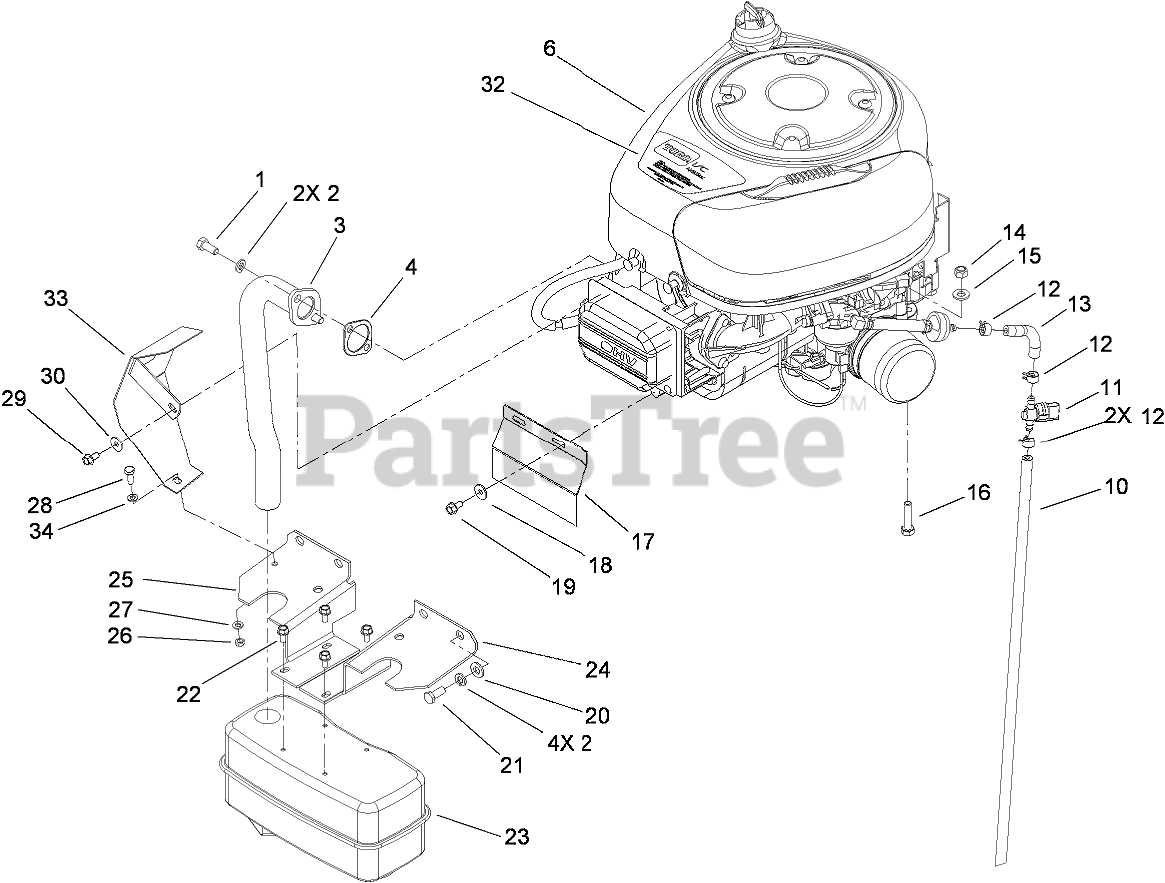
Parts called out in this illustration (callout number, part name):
1	SCREW-HH
2	WASHER-LOCK, SPRING
3	TUBE-EXHAUST
4	GASKET-EXHAUST
10	LINE-FUEL
11	VALVE-TANK, FUEL
12	CLAMP-LINE, FUEL
13	LINE-FUEL
14	NUT-LOCK, NI
15	WASHER-PLAIN
16	SCREW-HH
17	COVER-FRONT
18	WASHER-FLAT
20	WASHER-PLAIN
21	SCREW-HH
23	MUFFLER
24	GUARD-MUFFLER, LH
25	GUARD-MUFFLER, RH
26	NUT-HEX
27	WASHER-SPRING
28	SCREW-HH
30	WASHER-FLAT
32	DECAL-ENGINE
33	Cover-Manifold, Exhaust
34	WASHER-FLAT
